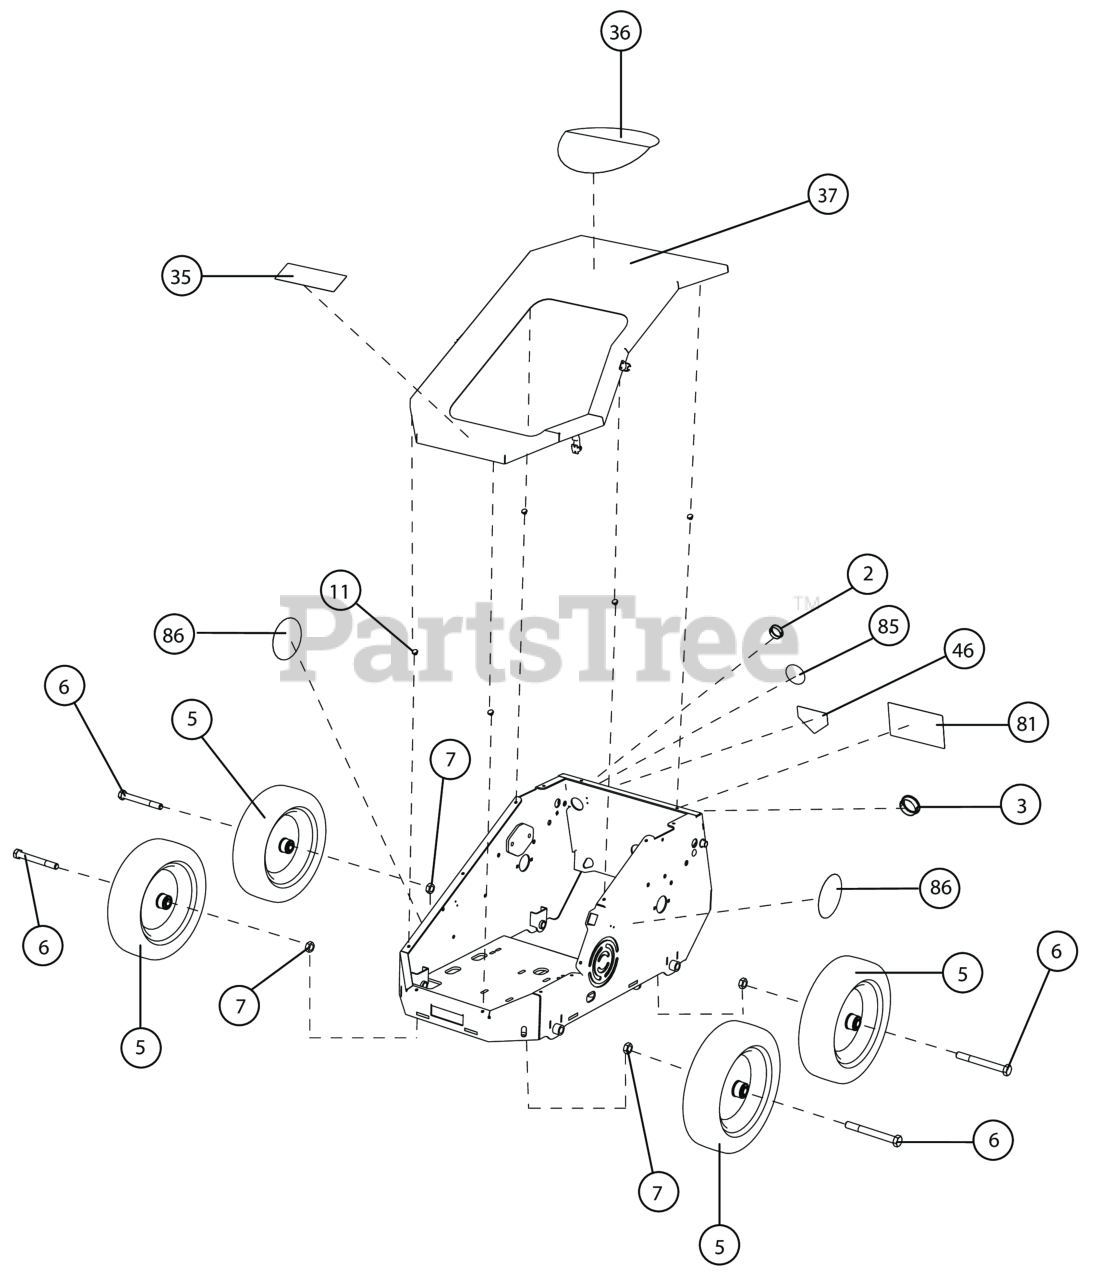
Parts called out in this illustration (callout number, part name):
2	BUSHING, SNAP 1.31" ID
3	BUSHING, SNAP 1.81" ID
5	SEE: 382606
6	SCR-CAP, HEX .625"-11 X 5.500" G5 ZP
7	NUT JAM, 5/8-11 ZP
11	RUBBER BUMPER PUSH IN
35	LABEL BADGING PLUGR PL415
36	LABEL BADGING 10" LOGO ROUND
37	WA, PL18 COVER W/DECALS
46	LABEL WARNING OPEI
81	LABEL AERATING INST PL
85	LABEL ROUND CORE T2V 2.5"
86	LABEL DECAL SM CIRCLE
